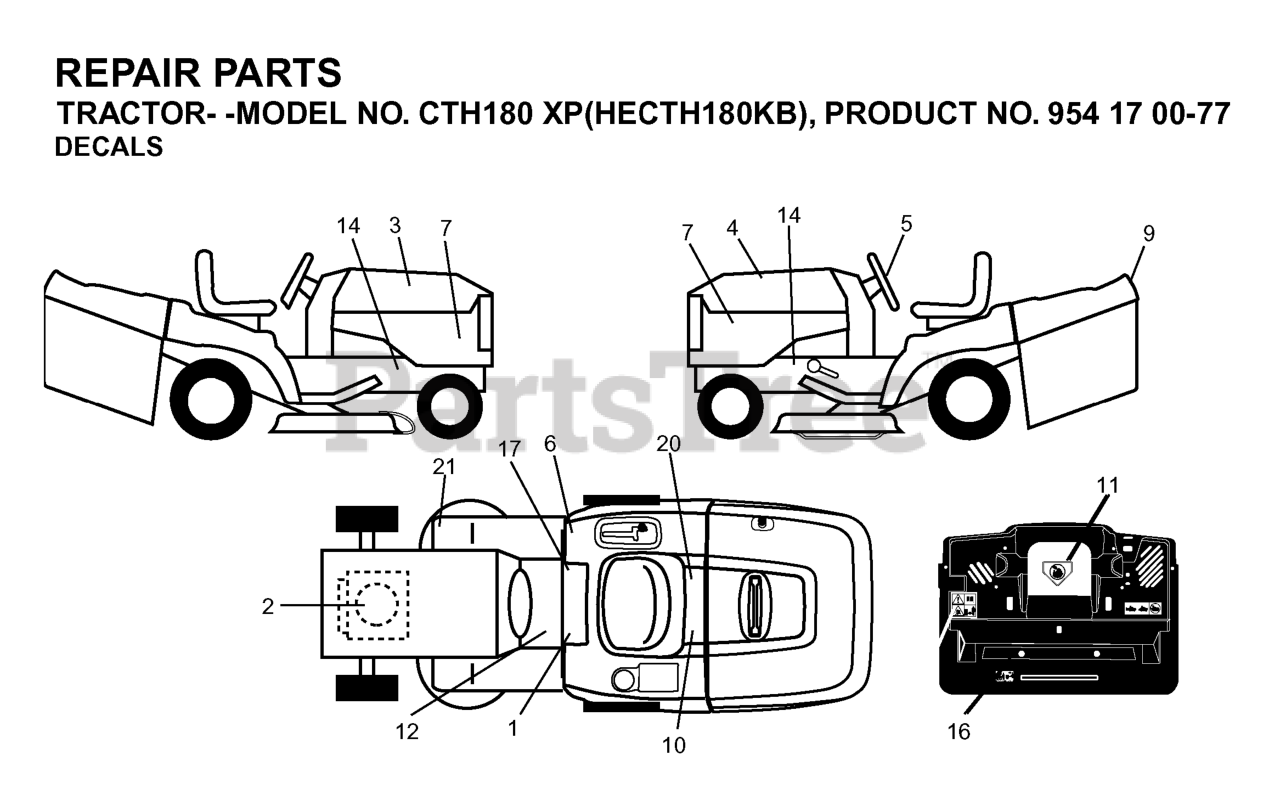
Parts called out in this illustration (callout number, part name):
1	DECAL READ OWNER'S MAN SYMS
2	DECAL ENGINE
5	DECAL.WHEEL.STEERING.HUSQ.PERM
6	Decal, Fender 100 DB/CE
9	DECAL FENDER HUSQ
10	DECAL BTRY SYMBOLS
11	DECAL.INTERNATIONL.CUTFINGER
12	DECAL
16	DECAL
17	DECAL PARK BRAKE
20	DECAL.BYPASS.FENDER.CRD.LT.YT
